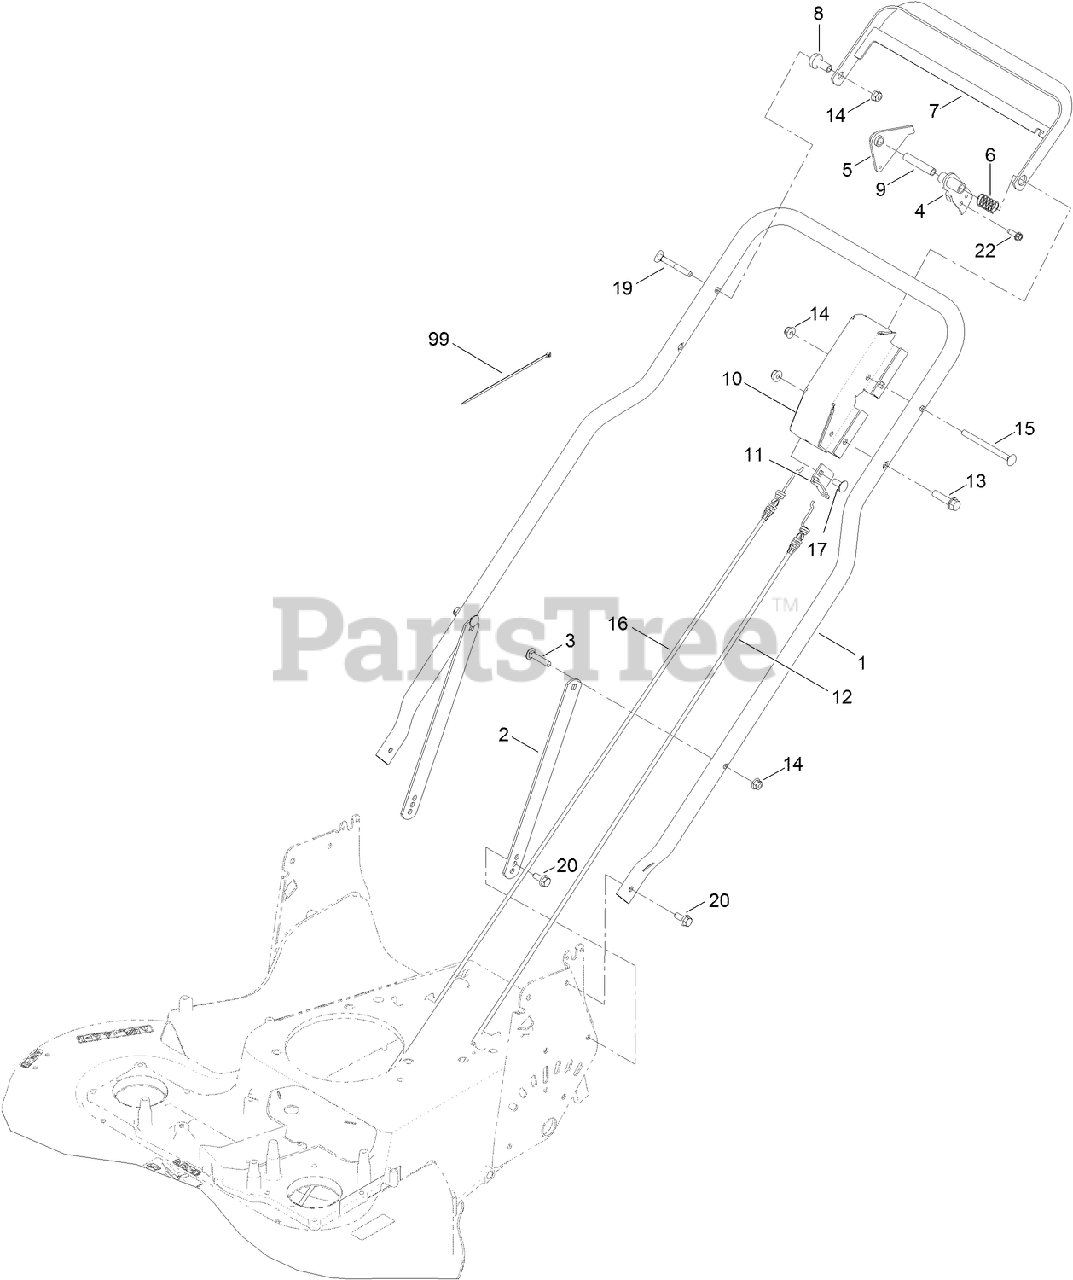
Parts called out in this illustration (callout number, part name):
2	SUPPORT-HANDLE
3	BOLT-CARR
4	BBC LEVER ASM
5	LEVER-TRACTION
6	SPRING-CONTROL
7	BAR-CONTROL
8	SPACER-SUPPORT
9	SPACER-BRACKET, CONTROL
10	BRACKET-CONTROL
11	BRACKET
12	CABLE-BRAKE
13	SCREW-HWH
14	NUT-HF, NI
15	SCREW-CARR
16	CABLE-TRACTION
17	SCREW-CARR
19	SCREW
20	SCREW-HHF
22	SCREW-HWHTF
99	TIE-CABLE
